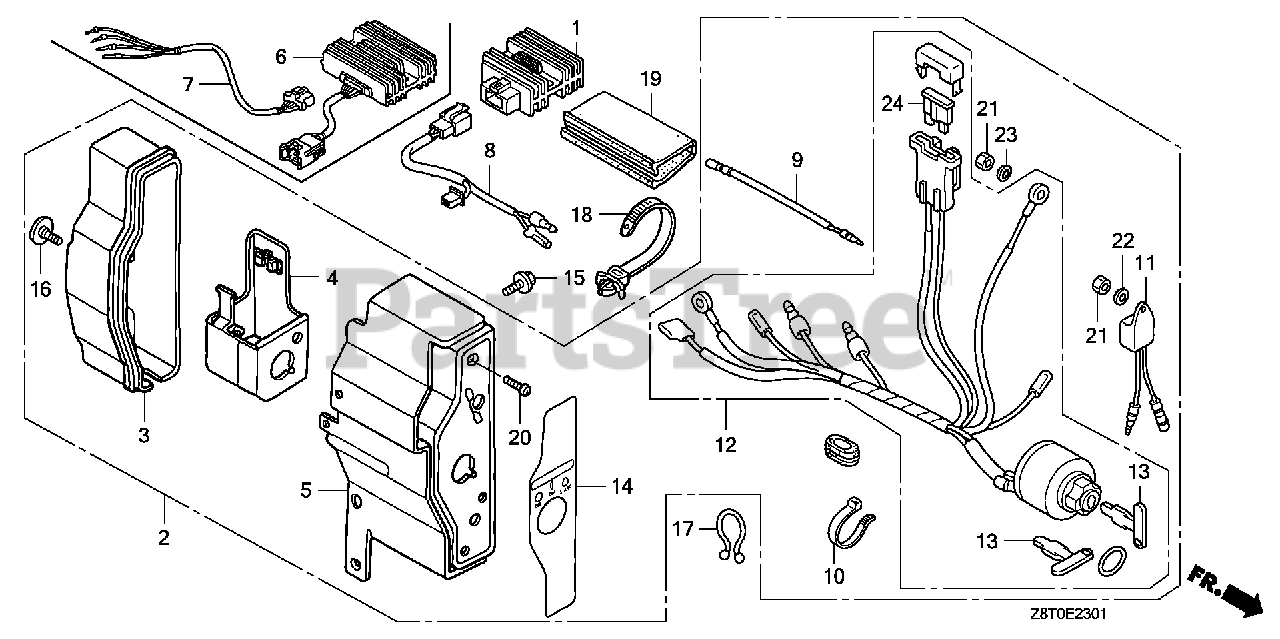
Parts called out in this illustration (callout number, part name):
2	BOX ASSY., CONTROL (18A) *NH1* (EXP-ALERT) (BLACK)
2	BOX ASSY., CONTROL (18A) *R280* (EXP-ALERT) (POWER RED)
3	CASE, CONTROL
4	BRACKET, CASE MOUNTING
5	PANEL, CONTROL *NH1* (BLACK)
5	PANEL, CONTROL *R280* (POWER RED)
6	RECTIFIER ASSY., REGULATOR (20A)
7	SUB-WIRE HARNESS ASSY.
9	SUB-WIRE HARNESS
11	ALERT UNIT, OIL
12	SWITCH ASSY., COMBINATION (18A-CHARGE)
13	KEY (HONDALOCK)
14	MARK, CONTROL BOX (EXP)
15	BOLT, FLANGE (6X12) (CT200)
16	SCREW, SPECIAL (6X12)
17	CLIP, PURSE LOCK
18	STRAP, CABLE (118MM) (BLACK)
19	TUBE, FASTENER (30MM)
20	SCREW, PAN (4X12)
21	NUT, HEX. (4MM) (SOURCE: VINTAGE PARTS INC.)
22	WASHER, PLAIN (4MM)
23	WASHER, SPRING (4MM)
24	FUSE, BLADE (25A)
